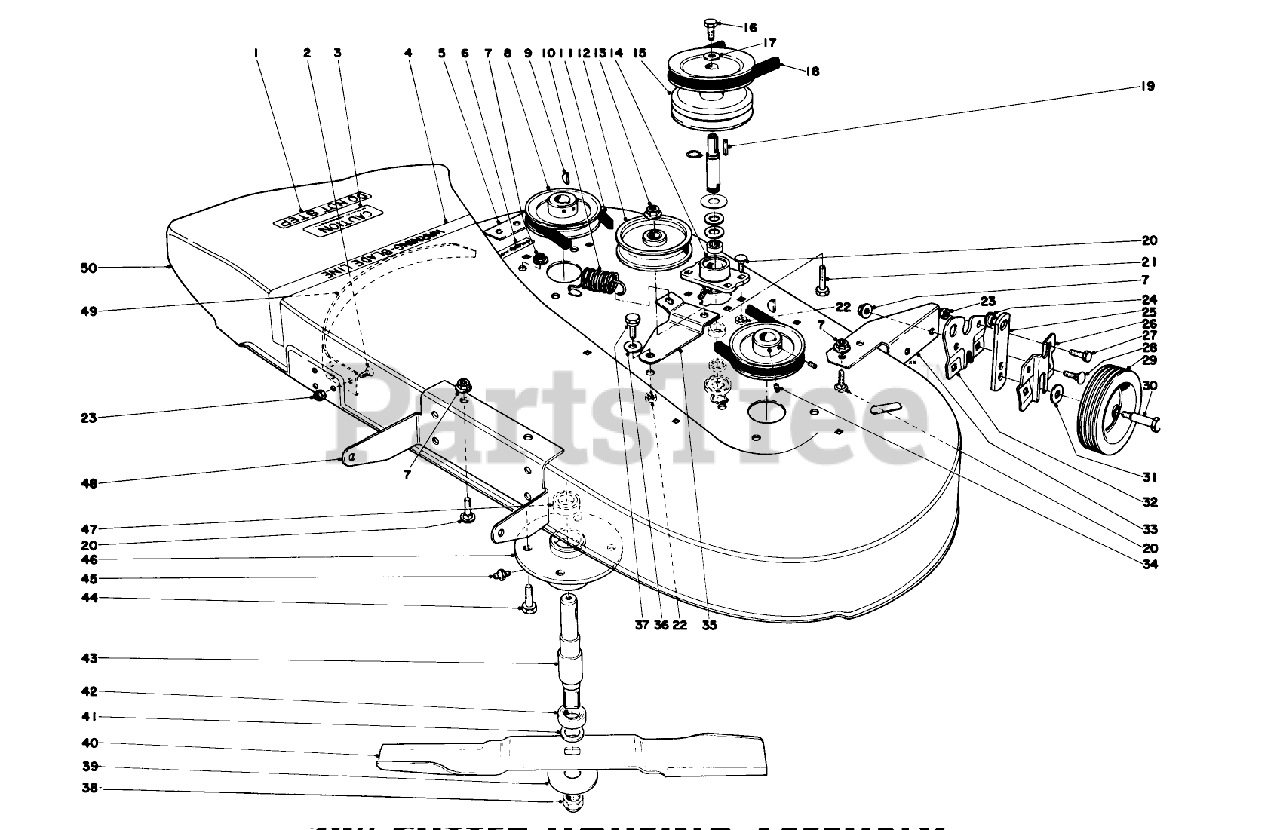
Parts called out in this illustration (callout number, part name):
1	Decal
2	SCREW-HSFH
3	Decal
4	Decal-Blade Line
5	Rear Bracket R.H.
6	Decal Height of Cut
7	NUT-HF
8	Pulley
9	KEY-WOODRUFF
10	Idler Lever Spring
13	NUT-HEX, SIDE DEFORM
14	Housing, Idler
15	Double Pulley
16	SCREW-HH
19	KEY-SQUARE
20	BOLT-CARR
21	SCREW-HH
22	NUT-LOCK, CONE
23	NUT-LOCK, CONE
24	Bushing
25	Slide Height Adj.
26	Retainer, Height Adj.
27	SCREW-HH
28	SCREW-CARR
30	Screw
32	Bracket R. H.
33	Rear Bracket L.H.
34	SCREW-SET
35	Idler Lever
36	Washer
37	Screw
38	NUT-SPECIAL
39	WASHER
41	WASHER
44	SCREW-HH
45	FITTING-GREASE
48	Bracket Front
49	Deflector Bar
